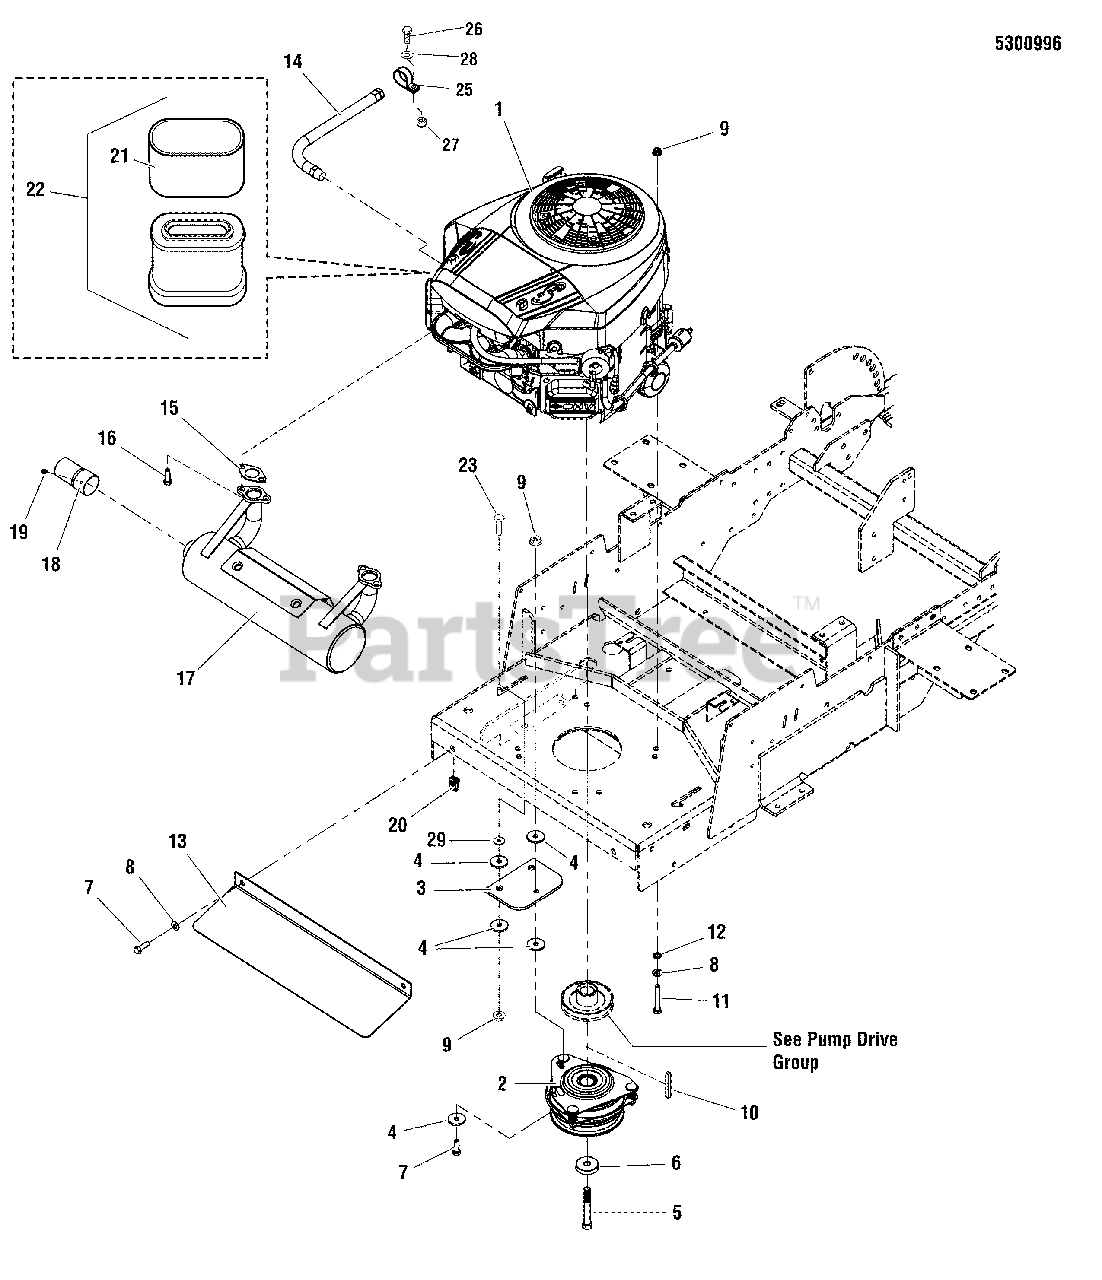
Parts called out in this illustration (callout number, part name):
1	* ENGINE, B&S, ELS
2	CLUTCH, #51110100, ELECTRIC, 1" SHAFT
3	CLUTCH ANCHOR PAD
4	WASHER, .34 X 1.25 X 10 GA
5	CAPSCREW, CRANKSHAFT, 7/16-20 x 3-1/4"YZ
6	SPACER, .45 X 1.62 X .37
7	BOLT, 5/16-18 X 1 GD5 YZ
8	WASHER, 5/16" SAE
9	NUT, 5/16-18 HEX NYLOCK FLANGE
10	KEY, 1/4" SQ. X 2 1/4
11	BOLT, 5/16-18 X 2-1/4" GD 5 YZ
12	WASHER, 5/16" INT. TOOTH LOCK
13	PLATE, HEAT SHIELD - RED
14	HOSE, OIL DRAIN
15	GASKET, EXHAUST
17	MUFFLER, B&S-ELS
18	EXTENSION, TAILPIPE, 3" - BLK
19	SCREW
20	BODY CLIP, 5/16-18 X 1/2 DEEP
21	PRE CLEANER (SV)
22	AIR CLEANER W/ PRE CLEANER (SV)
23	BOLT, 5/16-18 X 1-1/4 GD5 YZ
29	NUT, 5/16-18 HEX SERRATED FLANGE (LARGE)
